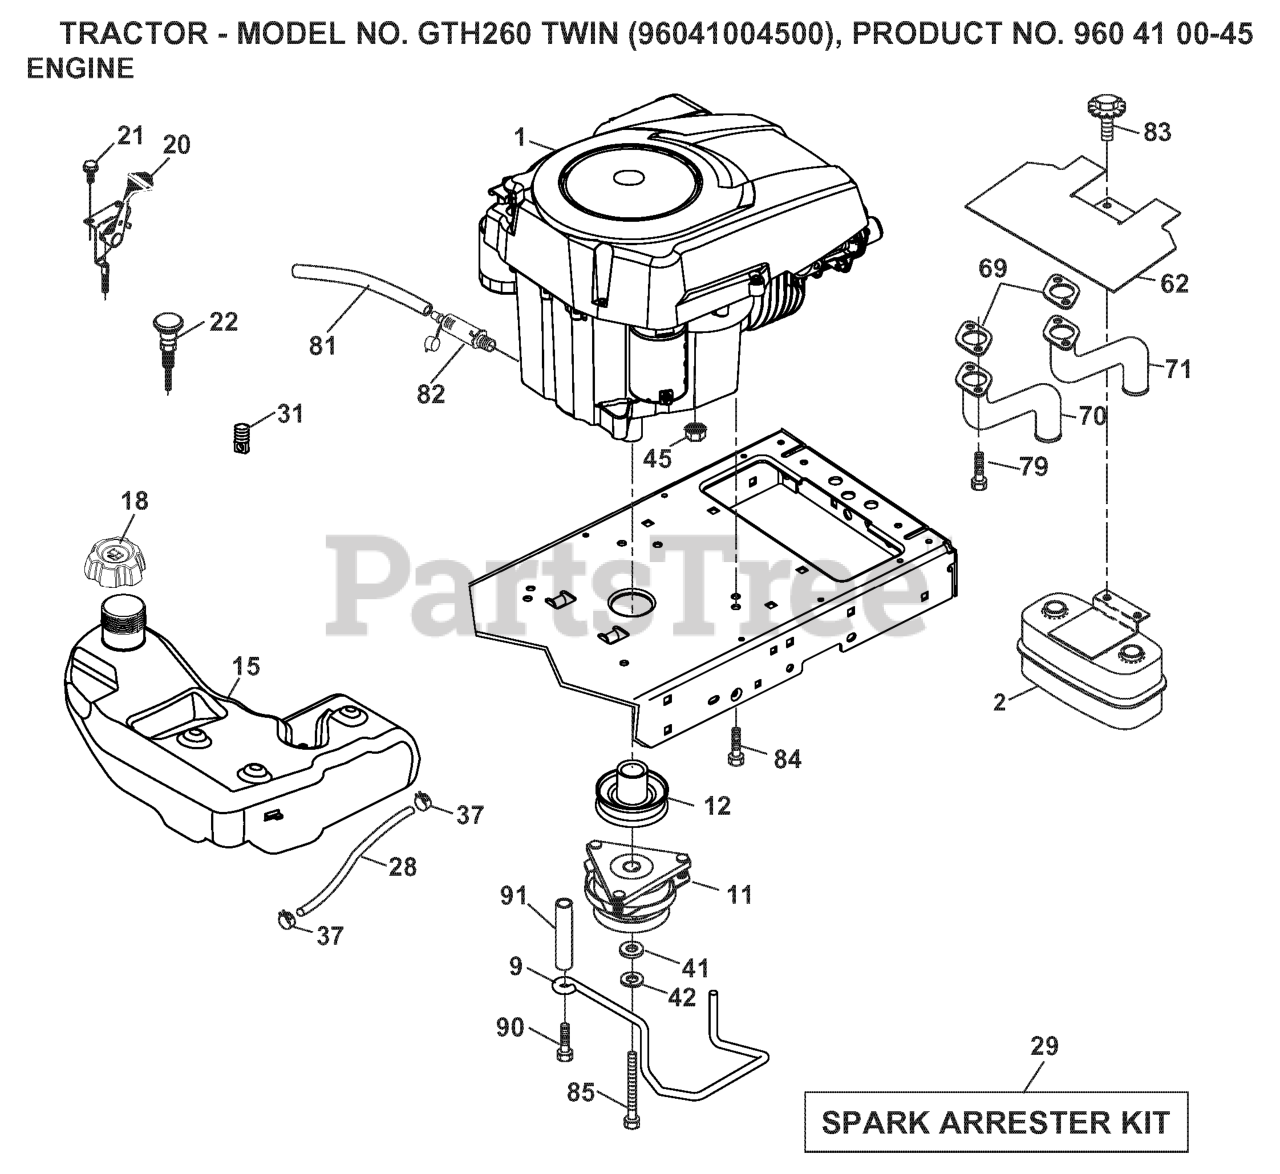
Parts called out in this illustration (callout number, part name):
2	MUFFLER.TWIN.CYL.LOW.TONE
9	KEEPER.BELT.ENGINE.4.2
11	CLUTCH MZ ZTR GT.48/54"1.125"
12	PULLEY ENGINE
15	TANK.FUEL.4GAL
18	CAP.FUEL.TANK.3"GREY
20	THROTTLE CONTROL
21	SCREW
22	CONTROL.CHOKE.ERGO.PUSH-IN.BLA
28	FUEL LINE 54"
29	KIT.SPARK ARRESTOR 794945 B&S
37	HOSE CLAMP
42	LOCKWASHER
45	NUT
62	RP SHIELD HEAT MUFFLER
70	RP.PIPE-EXHAUST LH
71	RP.PIPE-EXHAUST RH
79	SCREW.SOCKET HD.5/16-1
81	TUBE, DRAIN OIL ASM.
82	PLUG DRAIN OIL EASY
84	SCREW 3/8-16X1
85	BOLT HEX 7/16-20 X 3.75 GR. 5
87	BOLT.5/16-18UNCX1.W/SEMS.BLK
90	SCREW 3/8-16X1
91	BUSHING.1.375OD
